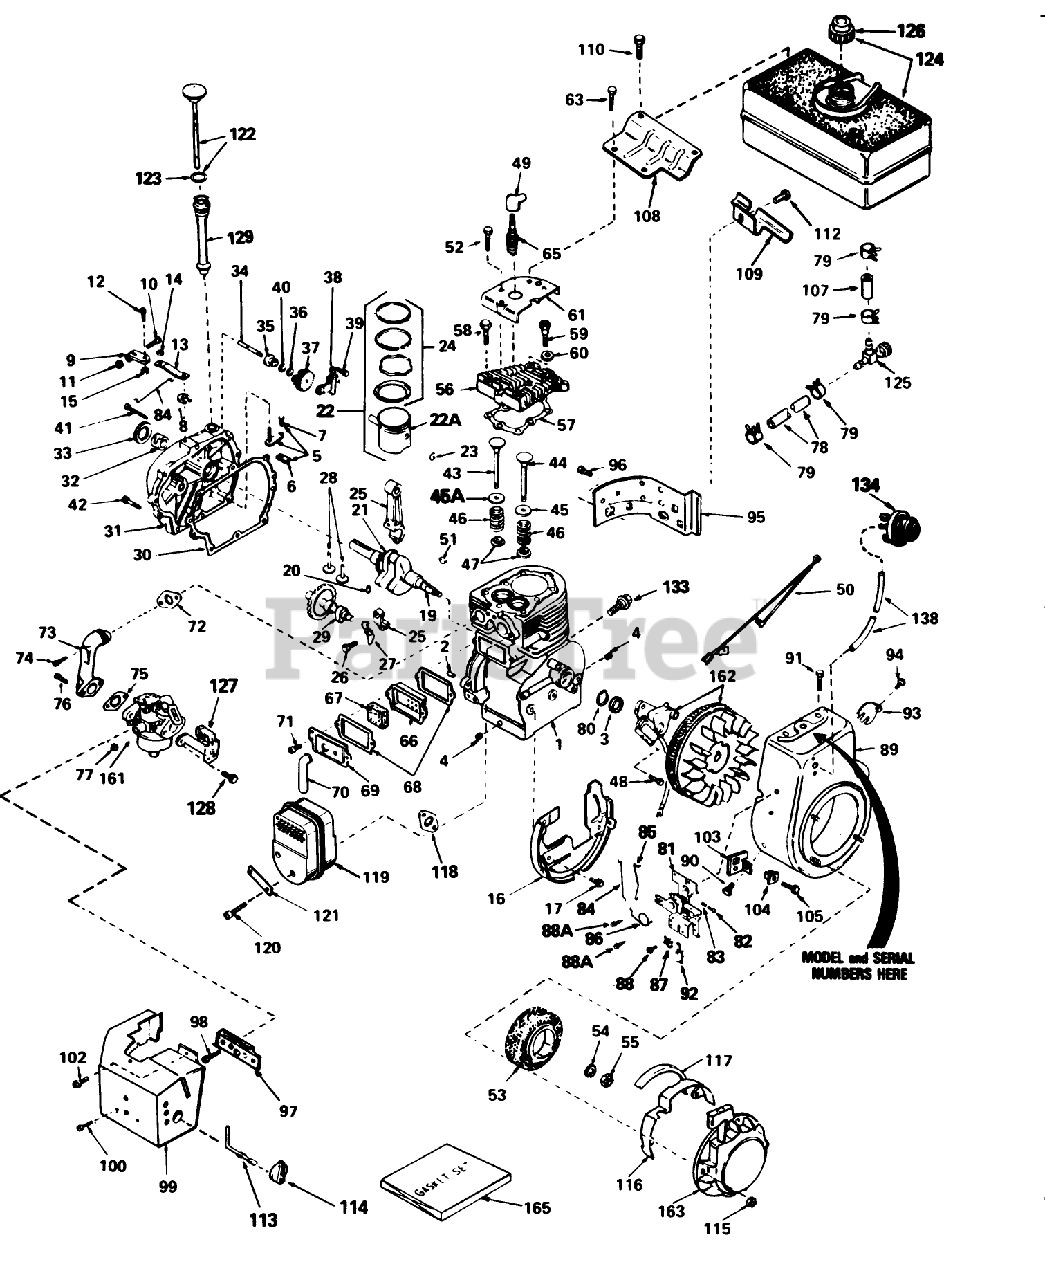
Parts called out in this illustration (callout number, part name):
1	Cylinder Assembly (Incl.Ref. #2, 3, 4 45A)
2	Pin-Dowel
3	Oil Seal
4	Plug-Drain, Oil (SQH 1/4-18)
5	Rod, Governor (Incl. Nos.62 63)
6	Yoke-Governor
7	Screw (6-40x5/16)
8	Ring-Retaining
9	Clamp-Lever, Governor
10	Screw
11	Nut-Lock
12	Screw
13	Lever-Governor
14	Washer-Lock
15	Nut-Lock
16	Baffle Blower Housing
17	Screw (1/4-20x19/32)
19	Crankshaft Assy. (Incl. Nos. 20 21)
20	Pin, Groove
21	Gear, Crankshaft
22	Piston, Pin Ring Assy.(Std.) (Incl. Ref. #24A, 25 26)
22	Piston, Pin Ring Assy. (.010 oversize) (Incl. Ref. #24A, 25 26)
22	Piston, Pin Ring Assy. (.020 oversize) (Incl. Ref. #24A, 25 26)
22A	Piston Pin Assy. (Std.) (Incl. Ref. #26)
22A	Piston Pin Assy. (.010 oversize) (Incl. Ref. #26)
22A	Piston Pin Assy. (.020 oversize) (Incl. Ref. #26)
24	Ring Set (Std.)
24	Ring Set (.010" OS)
24	Ring Set (.020" OS)
25	Rod Assy., Connecting (Incl. Nos. 10 18)
26	Bolt, Connecting Rod
27	Dipper-Oil
28	Lifter-Valve
29	Camshaft (Mech. Comp. Release)
30	Gasket, Cylinder Cover (Incl. Ref. #41)
31	Cover, Cylinder (Incl. Ref. #32, 33 34)
32	Bushing, Crankshaft
33	Seal, Oil
34	Shaft-Governor
35	Spool-Governor
36	Ring-Retaining
37	Governor Gear ASM
38	Bracket-Gear, Governor
39	Screw (10-24x1/2)
40	Washer-Flat
41	Screw (1/4-20x1-3/16)
42	Screw (1/4-20x1-11/16)
43	Valve, Intake (Std.) (Incl. Ref. #58)
43	Valve, Intake (1/32" oversize) (Incl. Ref. #58)
44	Valve, Exhaust (Standard)(Incl. No. 9)
44	Valve, Exhaust (1/32" oversize)(Incl. No. 9)
45	Cap-Spring, Valve
45A	Seal-Intake Valve
46	Spring-Valve
47	Keeper-Spring, Valve
48	Screw
49	Cover-Spark Plug
50	Wire, Ground
51	Key-Flywheel
52	Screw (1/4-20 X 5/8)
53	Hub Screen Assy., Starter
54	Washer-Belleville
56	Head Cylinder
57	Gasket-Cylinder Head
58	Screw (5/16-18x1-1/2)
59	Screw (5/16-18x1-25/32)
60	Washer-Flat
61	Cover, Cylinder Head
63	Screw
65	Plug, Spark (J17LM or equiv.)
65	Plug, Spark (Champion RCJ-8)
66	Body-Breather
67	Element-Breather
68	Gasket-Breather
69	Cover-Valve
70	Tube-Breather
71	Screw
72	Gasket-Intake
73	Pipe-Intake
74	Screw (T-30, 5/16-18x1-3/32)
75	Gasket-Carburetor To Intake Pipe
76	Screw (1/4-28x1)
77	Nut and Lock Washer (1/4-28)
78	Line-Fuel
79	Clamp-Line, Fuel
80	Gasket Stator
81	Control Assy., Remote Speed (Incl. Ref. #90 thru 93)
82	Screw
83	Spring-Compression
84	Link-Governor
85	Link-Throttle
86	Spring-Throttle
87	Conduit
88	Screw (10-32 x 3/8)
88A	Screw (10-32 x 1/2)
89	Housing, Blower
90	Screw, Hex Hd.
91	Screw (5/16-18x3/4)
92	Terminal
93	Screw
94	Screw (8-32 x 3/8)
95	Extension, Blower Housing
96	Screw
97	Bracket-Carburetor
98	Screw (8-32x27/64)
99	Cover-Carburetor
100	Screw (10-32 x 3/8)
102	Screw (10-32x1/2)
103	Bracket
104	Grommet
105	Screw
107	Line-Fuel (8.62)
108	Bracket-Tank, Fuel (Black)
109	Bracket-Tank, Fuel
110	Screw (1/4-15x7/8)
112	Screw (1/4-20x19/32)
113	Rod-Choke
114	Knob-Control
115	Nut and Lock Washer (1/4-28)
116	Guard, Starter
117	Seal, Snowguard
118	Gasket Exhaust
119	Muffler
120	Screw
121	62513 SNWTHWR W/284
122	Dipstick, Oil (Incl. Ref. #88)
123	O-Ring
124	Tank Assy., Fuel (Incl. No. 115)
125	Valve-Shut Off
126	Cap, Fuel
127	Bracket-Choke
128	Screw (10-32 x 1/2)
129	Tube Fill
133	Screw (1/4-20x1/2)
134	Primer Assy.
138	Line, Primer
161	Carburetor (Incl. Ref. #75)
162	Magneto (The complete magneto is not available as an assembly. The magneto number is shown for reference purposes only. Order component parts individually, as shown in parts list.)
163	Starter, Rewind
165	Gasket Set
